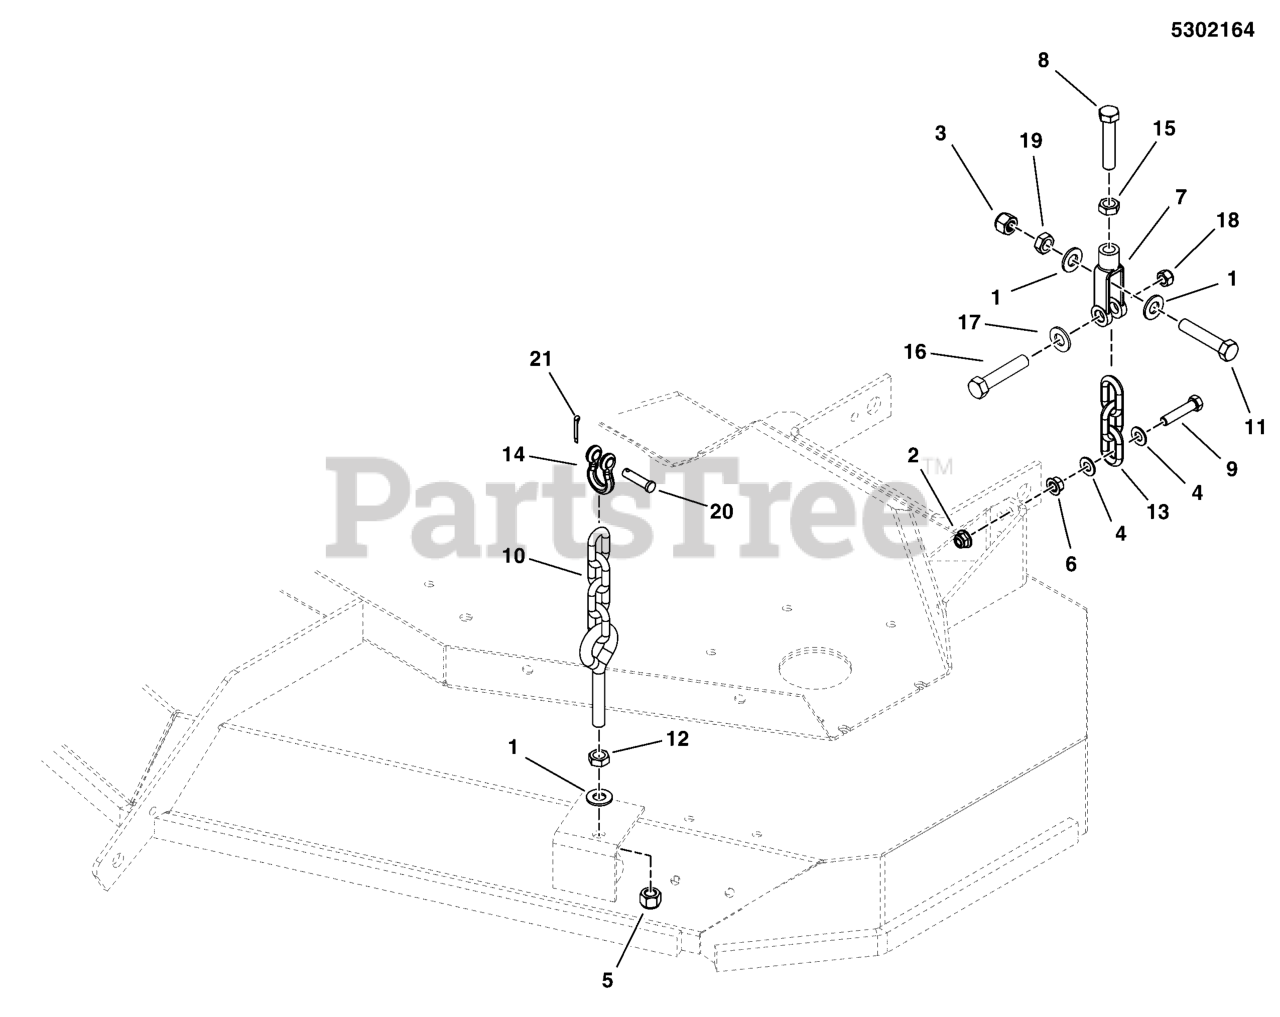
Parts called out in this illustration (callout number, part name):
1	WASHER, 1/2 SAE
2	NUT, 3/8 - 16 HEX NYLOCK FLANGE
3	NUT, 1/2-13 HEX NYLON LOCK
4	WASHER, 3/8 SAE
5	NUT, 1/2-13 HEX NYLON LOCK
6	NUT, 3/8-16 Hex Large Serrated Flange
7	CLEVIS, 1/2-20, STEEL, CLEAR ZINC
8	BOLT, 1/2-20 X 2-1/2, FLT
9	BOLT, 3/8-16 X 1-3/4" GD5 CZ
10	HANGER, FRONT DECK - 4 LINK, 5.5" EB
11	BOLT, 1/2-13 X 2-3/4 GD5 CZ
12	NUT, Hex, Jam, 1/2-13
13	CHAIN, 5/16" GD30, 3 LINKS
14	ROUND. PIN ANCHOR SHACKLE
15	NUT, 1/2-20 Hex Jam
16	CAPSCREW-HEX HD 7/16-14X2.000 G8 CL/ZC
17	WSHR,7/16 ID X .065 THK, FLAT,ZINC/CLEAR
18	NUT-HEX FLANGE 7/16-14 TWO WAY LK GA BLK
19	NUT, Hex, Jam, 1/2-13
20	PIN-ROUND HD DRILLED .375 X 1.500 BLK
21	* PIN, COTTER, 1/8" X 3/4
